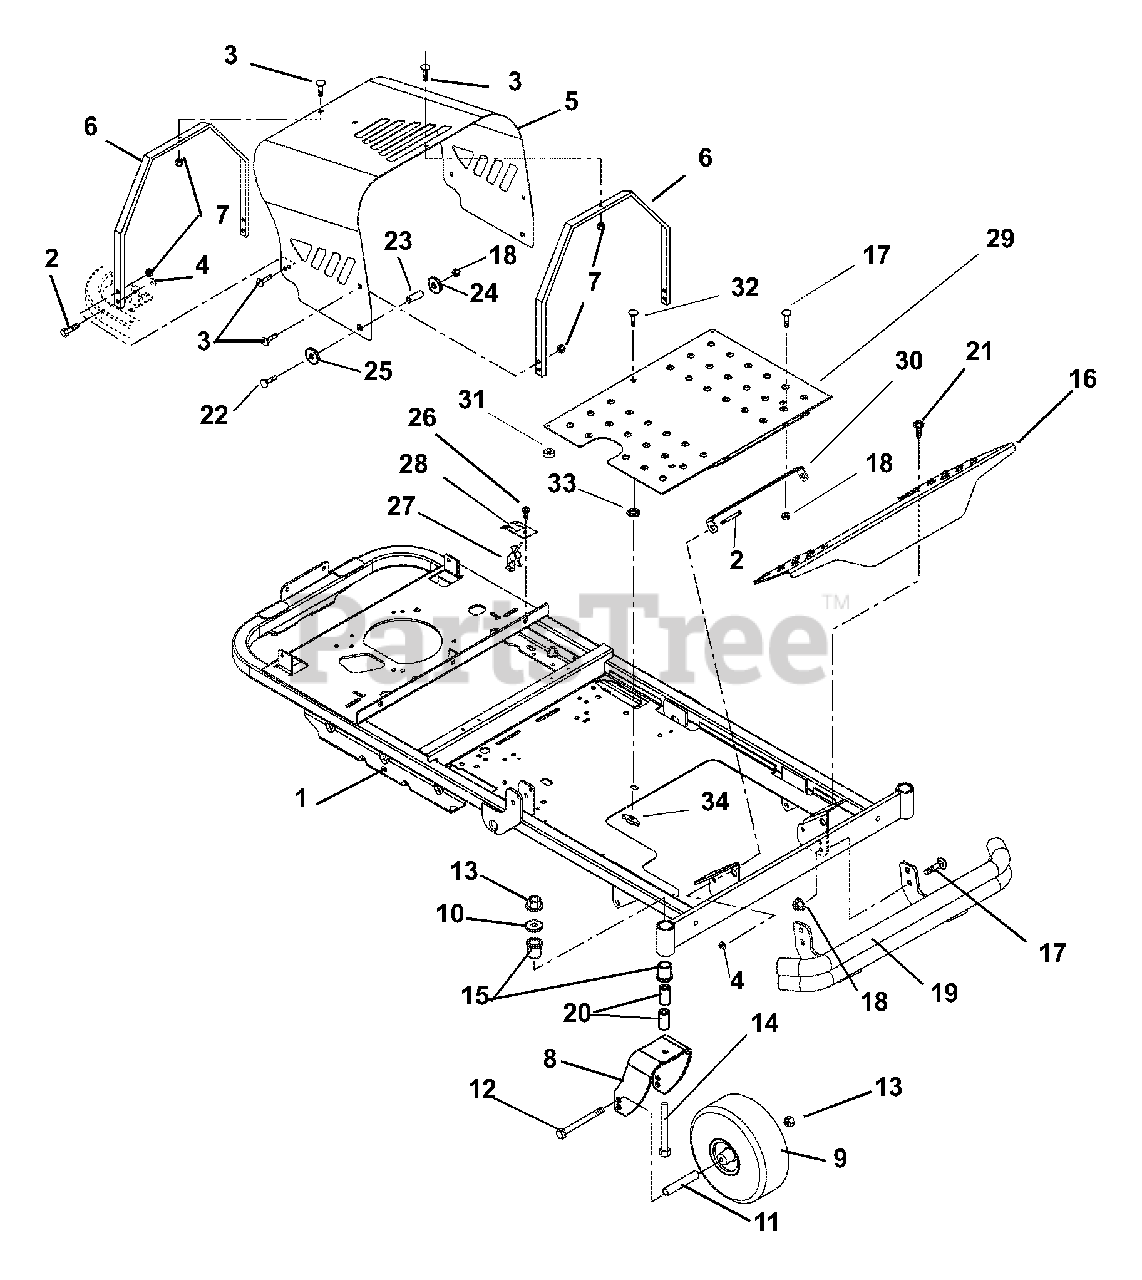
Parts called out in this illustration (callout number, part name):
1	Weldment, Frame
2	Bolt, Shoulder .375-16 x .135
3	Bolt, Round Head Square Neck .31-18 x .62
4	Nut, Locking Top Flange .38-16
5	Engine Hood
6	Brace, Hood
7	Nut, Locking Top Flange .31-18
8	Fork, Caster
9	Assembly, Tire 4 x 11- 4 Ply
10	Washer, Flat Steel .511 x 1.441 x .125
11	Spacer, Wheel
12	Bolt, Hex .50-13 x 6.50 Grade 5
13	Nut, Locking Top Flange .50-13
14	Bolt, Hex .50-13 x 5.00 Grade 5
15	Bushing, Flange 1.00 x 1.25 x 1.50 x 1.50
16	Foot Rest
17	Bolt, Round Head Square Neck .38-16 x 1.00 Grade 5
18	Nut, .38-16 Flange Nyloc
19	Bumper, Zoom
20	Spacer, Caster
21	Screw, Tap .31-18 x .50
22	Bolt, Round Head Square Neck .38-16 x 2.00 Grade 5
23	Hood Snap
24	Washer, Flat Steel .375 x 1.125 x .065
25	Washer, Flat Steel .531 x 1.06 x .095
26	Screw, Tap .25-20 x .50
27	Hood Clip
28	Bracket, Hood Clip
29	Plate, Deck Access
30	Bracket, Deck Access
31	Grommet, Bumper
32	Bolt, Round Head Square Neck .31-18 x 1.0 Grade 5
33	Nut, Push .312
34	Knob, Wing .312-18
